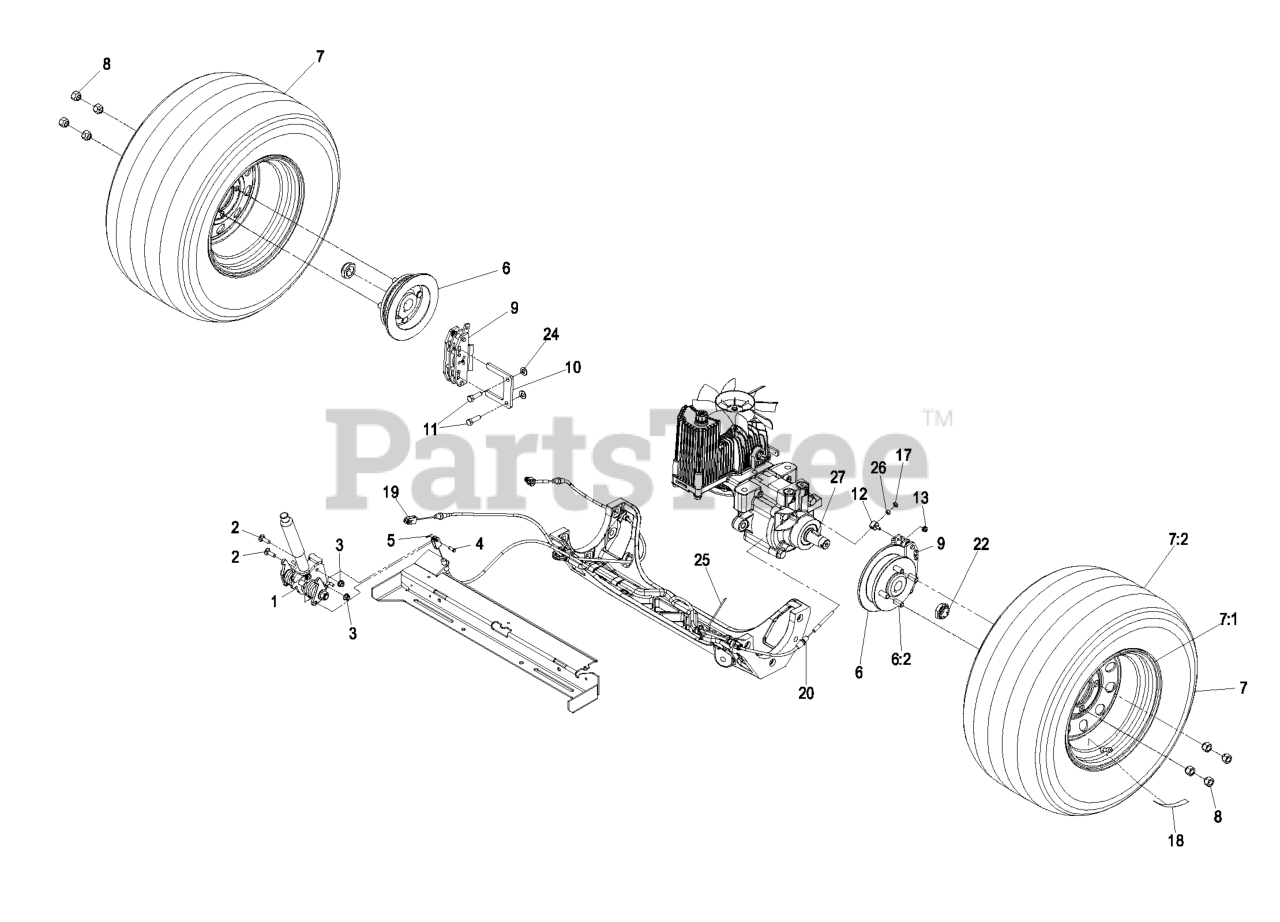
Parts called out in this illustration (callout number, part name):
1	BRAKE HANDLE ASM
2	BOLT-CARR
3	NUT-HF, NI
4	PIN-CLEVIS
5	PIN-COTTER
6	WHEEL HUB ASM
6:2	STUD-WHEEL
7	WHEEL AND TIRE ASM
8	NUT-LUG
9	CALIPER-BRAKE
10	PLATE-MOUNT, BRAKE
11	SCREW-LOCK, PATCH
17	NUT-LOCK, NI
24	WASHER-FLAT
25	TIE-CABLE
26	NUT-HEX
27	KEY-WOODRUFF
